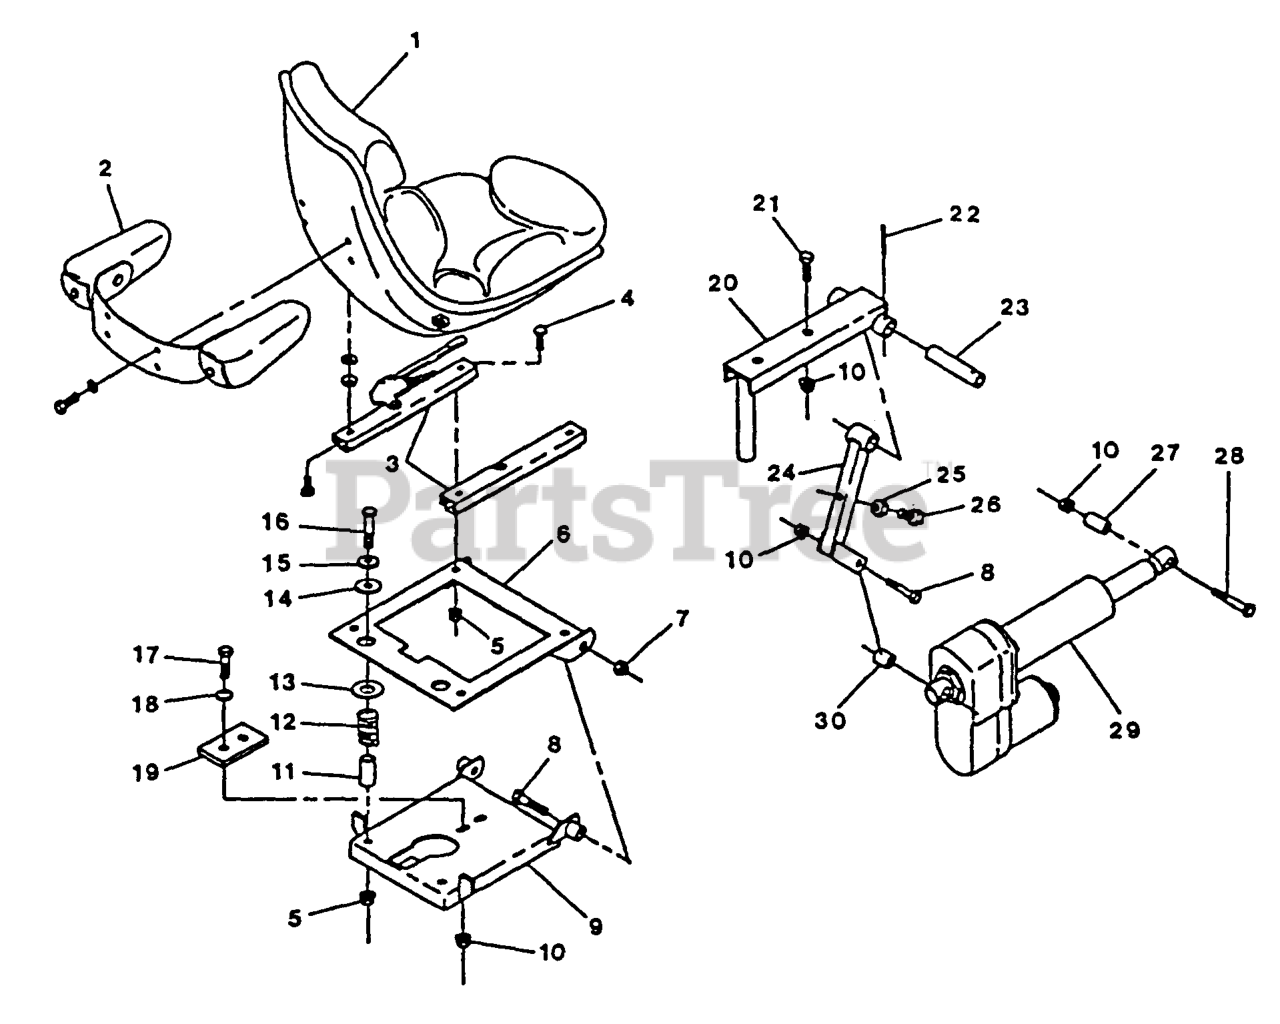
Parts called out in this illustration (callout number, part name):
11	BUSHING,SPRING GUIDE
12	SPRING-INDICATOR, REVERSE
13	WSHR,REVERSE INDICATOR
